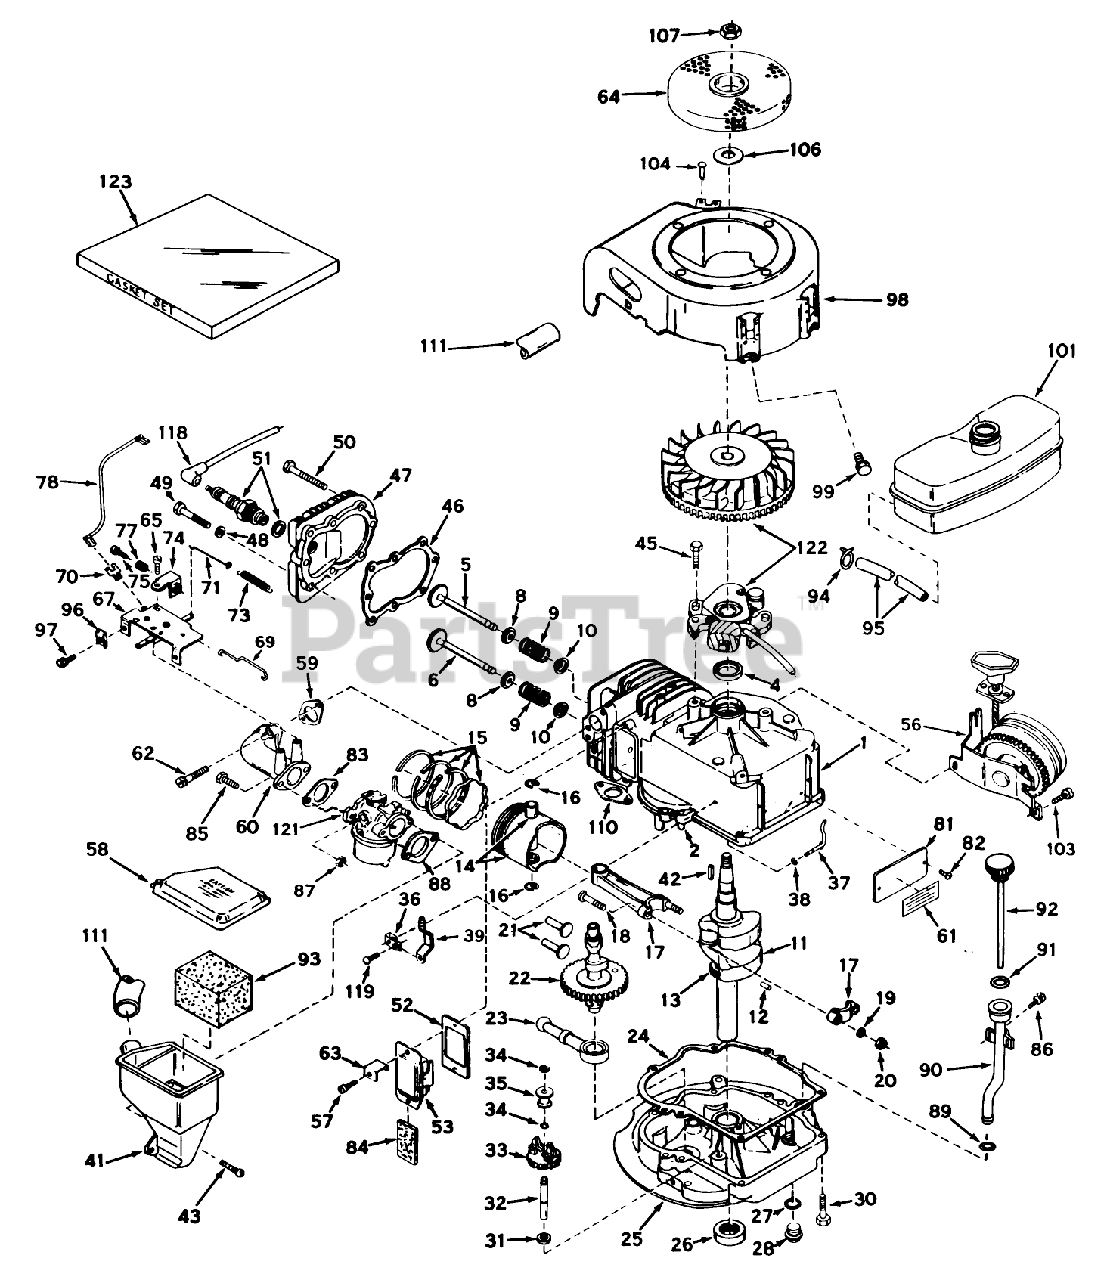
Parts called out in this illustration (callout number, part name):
1	Cylinder Assy. (Incl. Ref. 2 4)
2	Pin-Dowel
4	OIL SEAL
5	Valve, Intake (Incl. Ref. #38, 39 40) (Std.)
5	Valve, Intake(1/32"overs.)(Incl. Ref. 8, 9 10)
6	Valve, Exhaust (Standard)(Incl. Ref. 8, 9 10)
6	Valve, Exhaust (1/32" Overs.(Incl. Ref. 8, 9 10)
8	Cap-Upper Valve Spring
9	Spring-Valve
10	Cap-Valve, Spring
11	Crankshaft Assy. (Incl. Ref. 12 13)(Model LAV35-40455H)
12	Pin, Groove
13	Gear, Crankshaft
14	Piston Pin Assy. (Standard)(Incl. 2 of No. 16)
14	Piston Pin Assy. (.010 overs.)(Incl. 2 of Ref. 16)
14	Piston Pin Assy. (.020 overs.)(Incl. 2 of Ref. 16)
15	Ring Set, Piston (Std.)
15	Ring Set, Piston (.010 o.s.)
15	Ring Set, Piston (.020 o.s.)
16	Ring-Retaining, Piston Pin
17	Rod Assy., Connecting (Incl. Ref. #17)
18	Bolt, Connecting
19	Washer
20	LOCKNUT
21	Lifter-Valve
22	Camshaft
23	Oil Pump ASM
24	Gasket, Mounting
25	Flange Assy., Mounting (Incl. Ref. 26, 27, 28 32)
26	Seal Oil
27	Gasket-Oil Drain
28	Plug Oil Drain
30	Screw (1/4-20 x 1-1/4)
31	Washer-Flat
32	Shaft-Governor
33	Governor Gear ASM
34	Ring-Retaining
35	Spool-Governor
36	Clamp-Lever, Governor
37	Rod, Governor (Incl. No. 36)
38	Washer-Flat
39	Governor Lever
41	Body, Air Cleaner
42	Key Flywheel
43	Screw, Fil. Hd. Sems
45	Screw
46	Gasket-Cylinder Head
47	CYLINDER HEAD
48	Washer
49	Screw
50	Screw Hex Hd. Cap
51	SPARK PLUG
52	Gasket Breather
53	Breather Assembly (Incl. Nos. 52 84)
56	Starter, Side Mount
57	Screw
58	Cover, Air Cleaner
59	Gasket, Intake
60	Pipe, Intake
61	480B GIL SNWTHWR O/
62	Screw (1/4-20 x 1)
63	Retainer Clip
64	Screen, Flywheel
65	Screw (10-24 x 9/16)
67	Control Assy., Speed
69	Link Governor
70	Terminal
71	Link-Governor
73	Spring, Governor
74	Brachet, Control
75	Screw, Hex Hd.
77	Spring
78	Wire, Ground
81	IDENTIFICATION PLATE
82	Stud
83	Gasket
84	Element-Breather
86	Screw (10-32 x 1/2)
87	Nut and Lock Washer (1/4-28)
88	Gasket-Air Cleaner
89	O-Ring
90	Tube Assy., Oil Fill
91	O-Ring
92	Dipstick, Oil
93	Element, Air Cleaner
94	Clamp-Line, Fuel
95	Line-Fuel (8.62)
96	Conduit
97	Screw (10-32 x 3/8)
98	Housing, Blower
99	Screw (1/4-20x19/32)
101	Tank, Fuel
103	Screw (1/4-20 x 1/2)
104	Rivet
106	Washer
107	Hex Nut
110	Gasket Exhaust
111	Tube, Air Cleaner
118	Cover-Spark Plug
119	Screw
121	Carburetor
122	Magneto
123	Gasket Set
